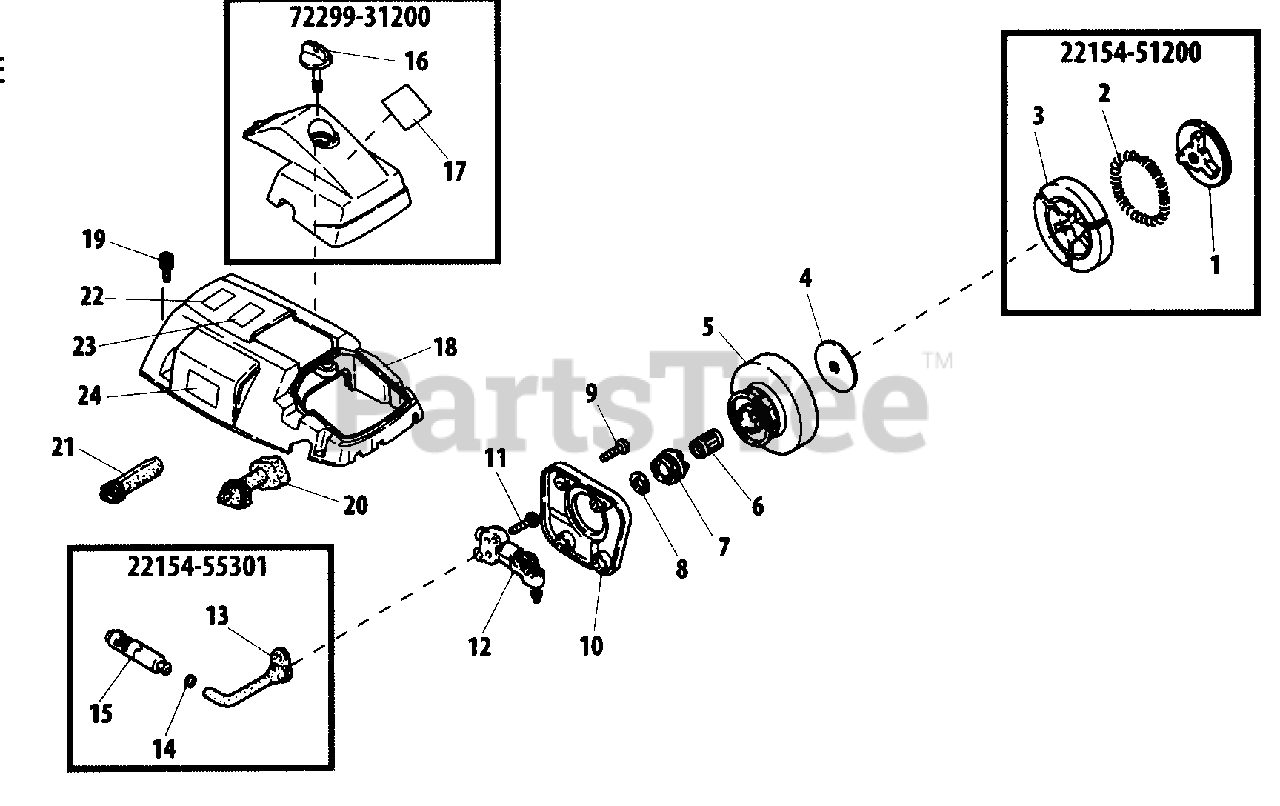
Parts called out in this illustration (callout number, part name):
1	HUB, CLUTCH - OUTER
2	SPRING, CLUTCH
3	SHOE, CLUTCH
4	HUB, CLUTCH - INNER
5	DRUM, CLUTCH
6	BEARING, NEEDLE
7	GEAR
8	WASHER, THRUST
9	SCREW - 4X12
10	COVER, PUMP
11	SCREW - 4X12
12	AUTO-OILER ASSY
13	PIPE - OIL
14	CLIP
15	FILTER, OIL
16	THUMBSCREW
17	LABEL - CAUTION
18	COVER, ENGINE
19	SCREW - 4X16
20	GROMMET (EPA/CARB)
21	GROMMET
22	LABEL - CAUTION
23	LABEL - CAUTION
24	LABEL - CAUTION
22154-51200	CLUTCH ASSY
22154-55301	OIL FILTER ASSY
72299-31200	AIR FILTER COVER ASSY
